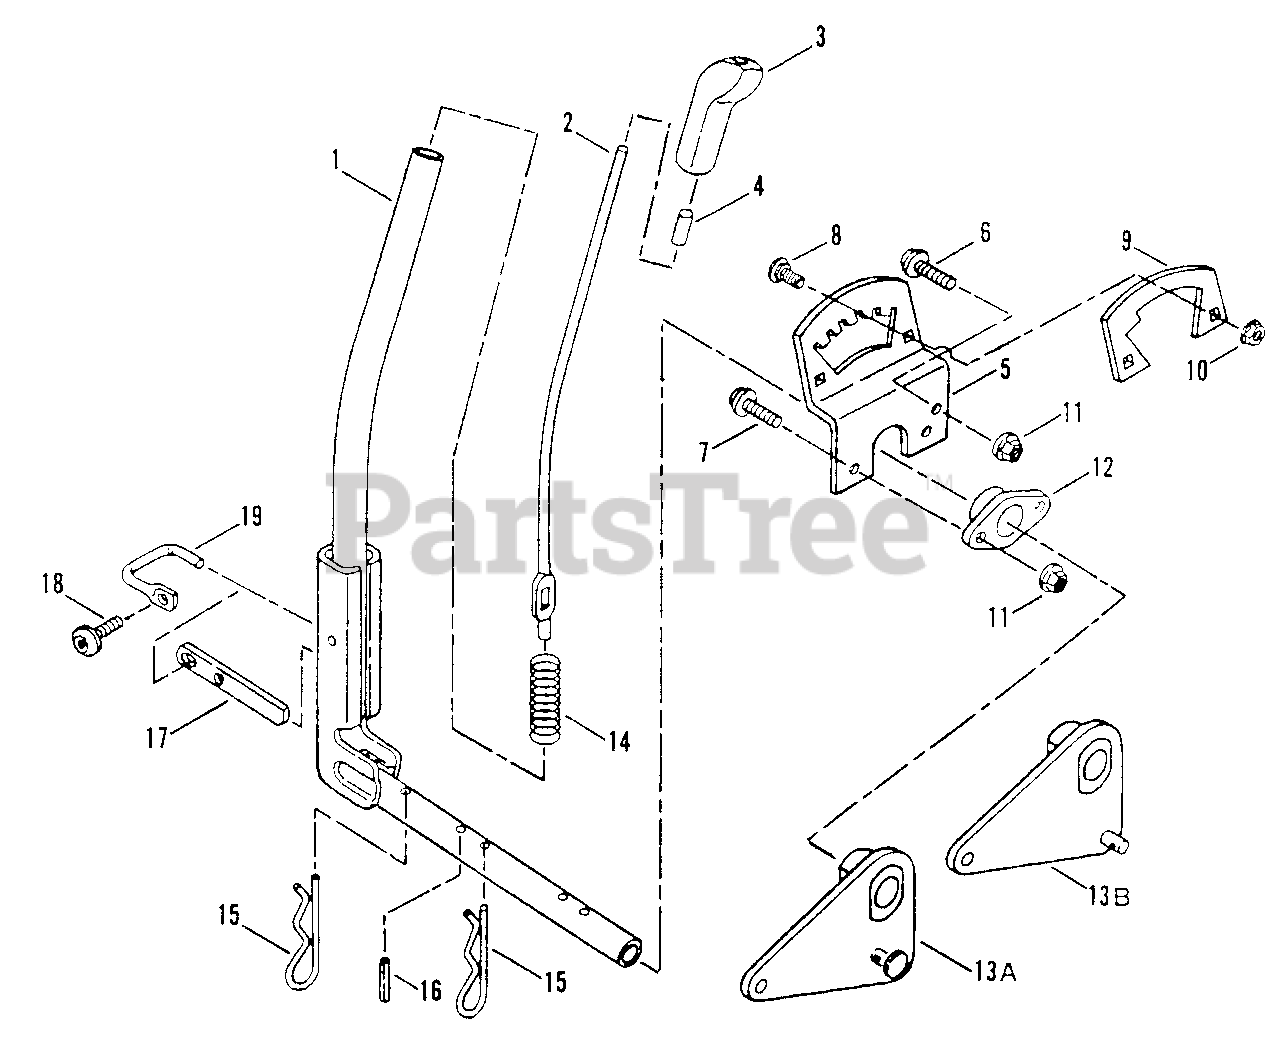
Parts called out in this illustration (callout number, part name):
1	LEVER, Implement Lift
2	ROD, Lift Lever
3	KNOB, Lift Lever
4	CAP, Lift Lever Rod
5	QUADRANT, Lift Lever
6	SCREW, 5/16-18 x 5/8" Truss Head (Torx)
7	SCREW, 5/16-18 x 7/8" Truss Head (Torx)
8	BOLT, 1/4-20 x 1/2" Short Neck Carriage, Grade 5
9	DETENT, Highcut Lockout
10	NUT, 1/4-20 Hex Flange Lock, Grade 5
11	NUT, 5/16-18 Hex Flange Lock, Grade 5
12	PIVOT, Lift Lever
13A	BELLCRANK, Lift Lever
13B	BELLCRANK, Lift Lever
15	PIN, Hair, 5/32 x 2 5/8"
16	PIN, Dowel, 1/4 x 1 1/8"
17	DETENT, Latch
18	SCREW, 1/4-20 x 5/8" Truss Head (Torx)
19	LATCH, Pivot
